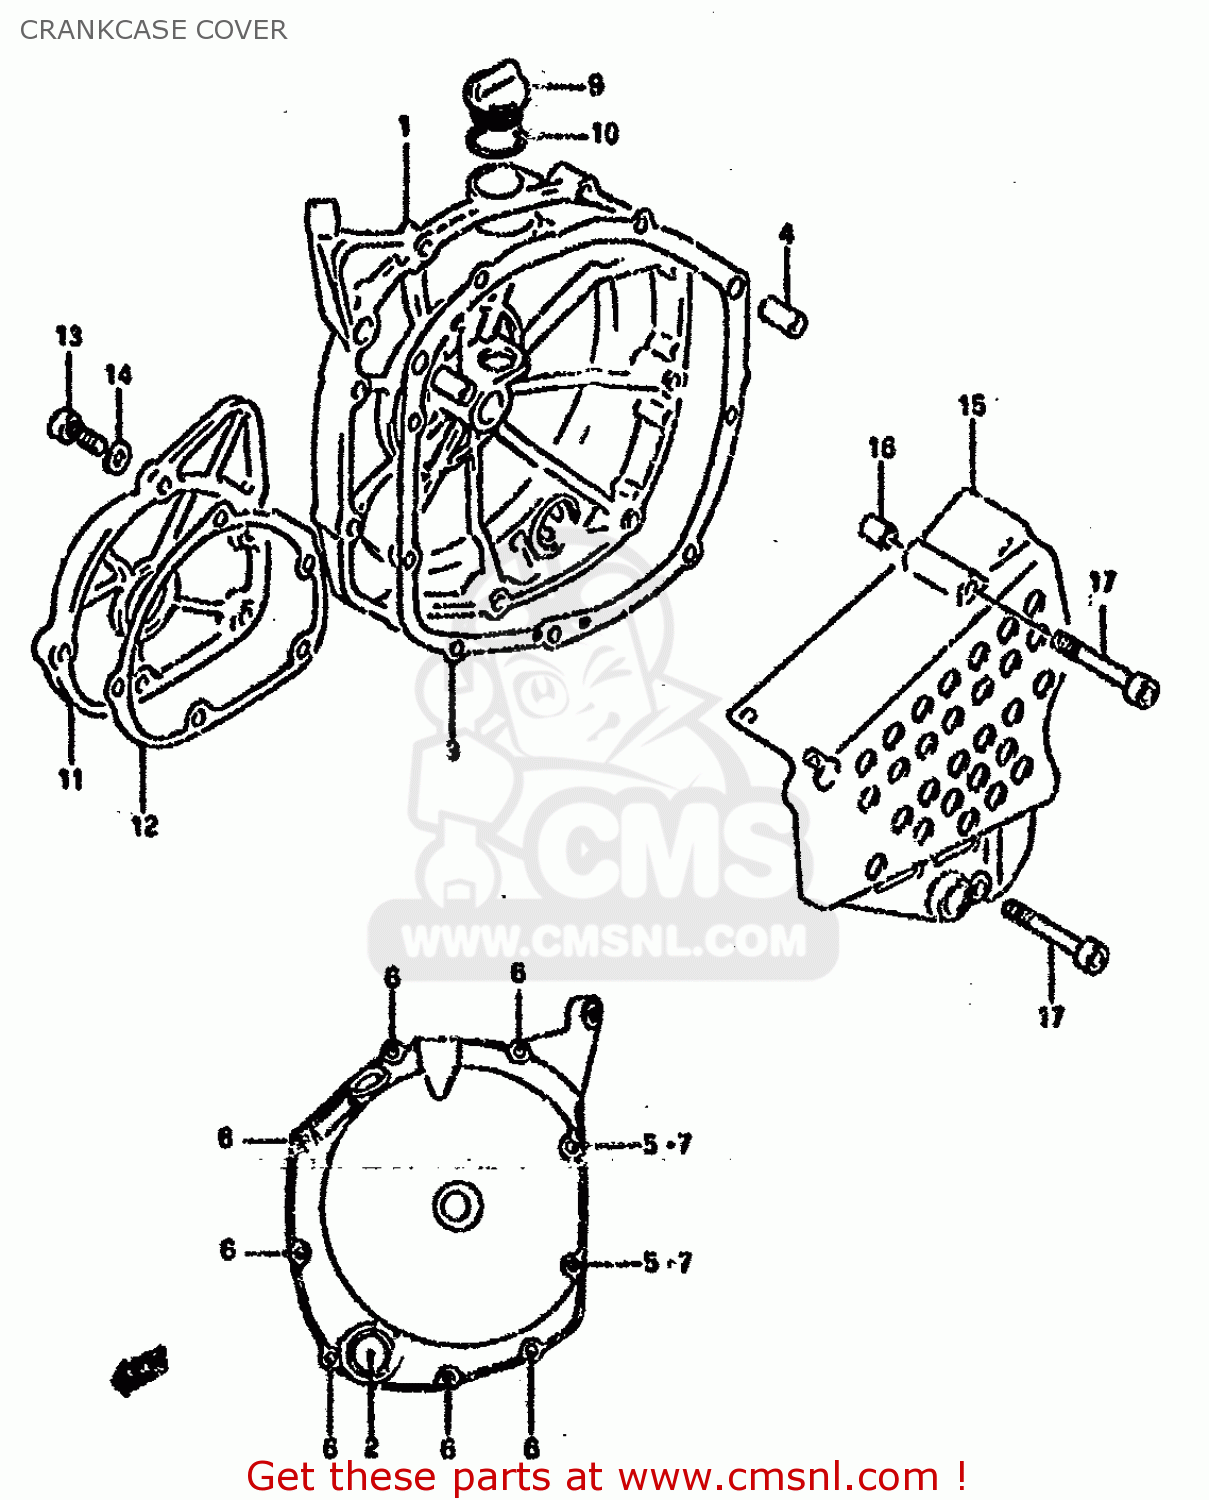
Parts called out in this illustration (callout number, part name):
1	COVER,CLUTCH
2	LENS,OIL LEVEL CHECK
3	GASKET,CL COVER (NAS)
4	PIN
5	GASKET(5.8X11X1.2) (NAS)
6	BOLT,CL.COVER
7	BOLT
8	BOLT
9	PLUG
10	O RING(D:3.1,ID:16.8)
11	COVER,SIGNAL GENERATOR
12	GASKET,SIGNAL GEN COVER
13	BOLT(6X22)
14	GASKET(5.8X11X1.2) (NAS)
15	COVER,ENGINE SPROCKET
16	PIN
17	BOLT(6X50)
